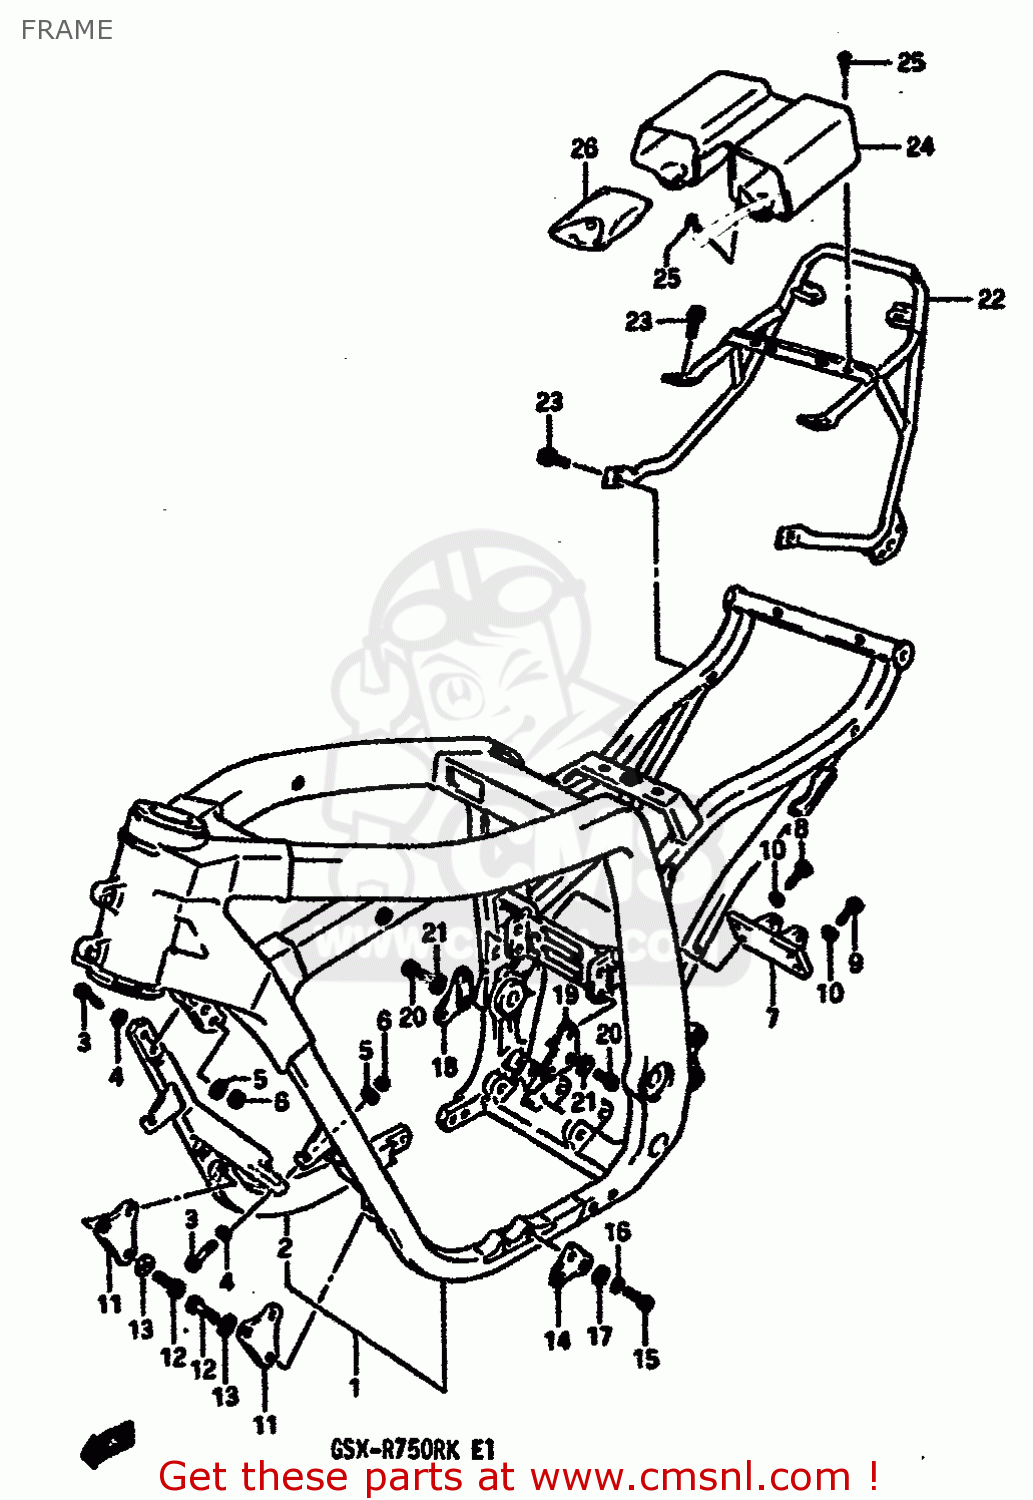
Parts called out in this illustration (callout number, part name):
1	FRAME SET
2	TUBE,FRAME DOWN RH
3	BOLT, LH
4	WASHER (10.1X21X2.3)
5	WASHER
6	NUT
7	BRACKET,RCU
8	BOLT 10X27
9	BOLT, LH
10	WASHER
11	PLATE,ENGINE MOUNTING
12	BOLT, FRONT LH
13	WASHER (8.2X20X1.6)
14	PLATE,ENGINE MOUNT NO.2
15	BOLT
16	WASHER,LOCK
17	WASHER (8.2X20X1.6)
18	PLATE,ENGINE MOUNT NO.3,R
19	PLATE,ENGINE MOUNTING NO
20	BOLT, FRONT LH
21	WASHER (8.2X20X1.6)
22	GRIP,REAR
23	BOLT
24	HOLDER,TOOL
25	SCREW 6X12
26	TOOL SET
